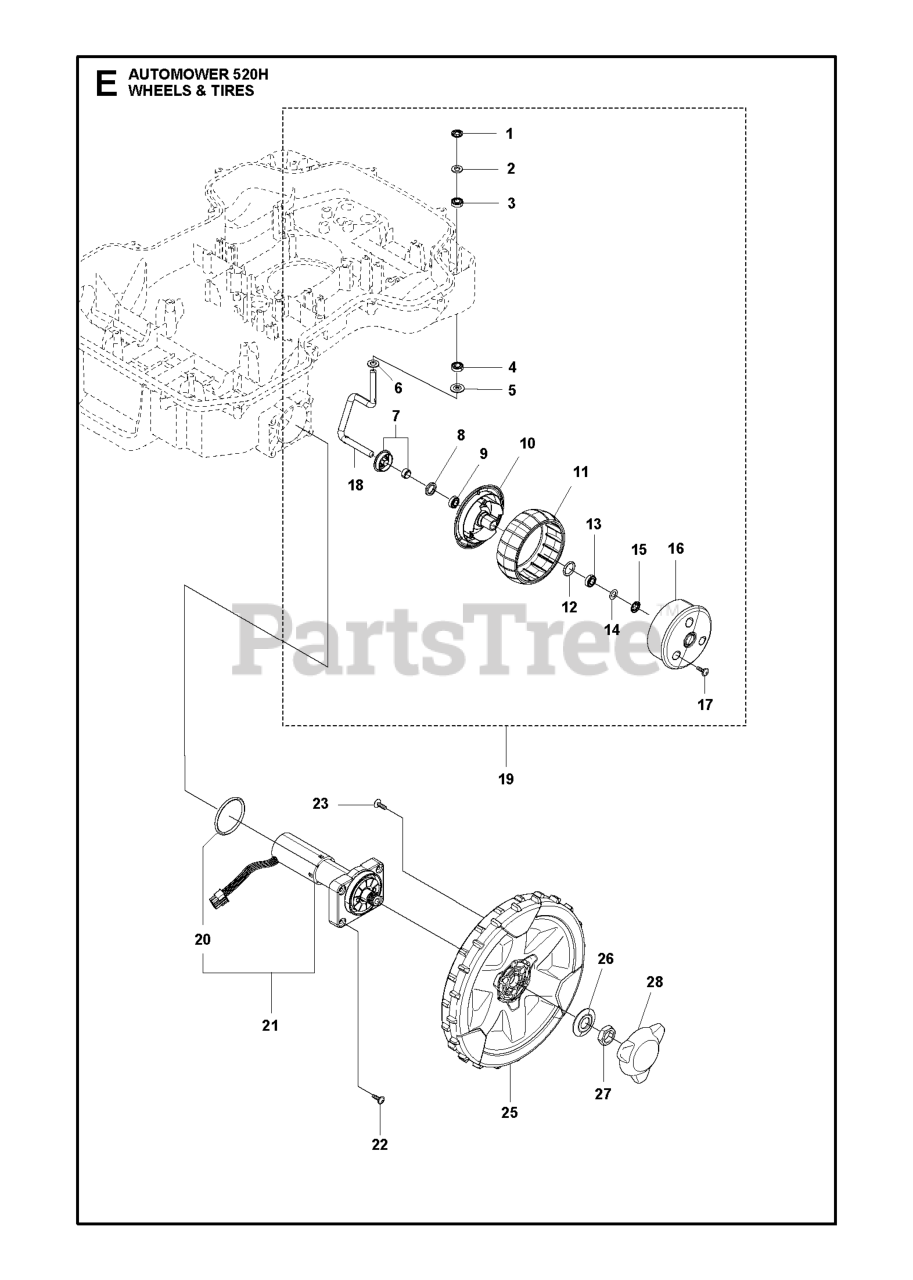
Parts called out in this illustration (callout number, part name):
1	LOCKWASHER PUSH-ON TYPE P 8 BV
2	WASHER DIN 988 13X8X0.5
3	BALL BEARING SINGLE ROW S688
4	BALL BEARING SINGLE ROW S688
5	WASHER FRONT WHEEL CENTER HOLE
6	WASHER DIN 988 13X8X0.5
7	SHIELD KIT
8	SEALING 12X18X3
9	BALL BEARING SINGLE ROW S688
10	WHEEL FRONT WHEEL INSIDE
11	WHEEL RUBBER TYRE
12	O-RING 2,62X15,54
13	BALL BEARING SINGLE ROW S688
14	WASHER DIN 988 13X8X0.5
15	LOCKWASHER PUSH-ON TYPE P 8 BV
16	WHEEL FRONT WHEEL OUTSIDE
17	SCREW 14MM
18	SPINDLE SPINDLE FRONT WHEEL RI
19	Wheels
20	O-RING LIGHT GREY
22	SCREW ITXPANT
23	SCREW ITXPANT
25	WHEEL ASSY D249 HVA LIGHT GREY
26	WASHER WASHER REAR WHEEL 16X40
27	HEXAGON THIN NUT
28	HUB CAP REAR WHEEL NO CENTER P
